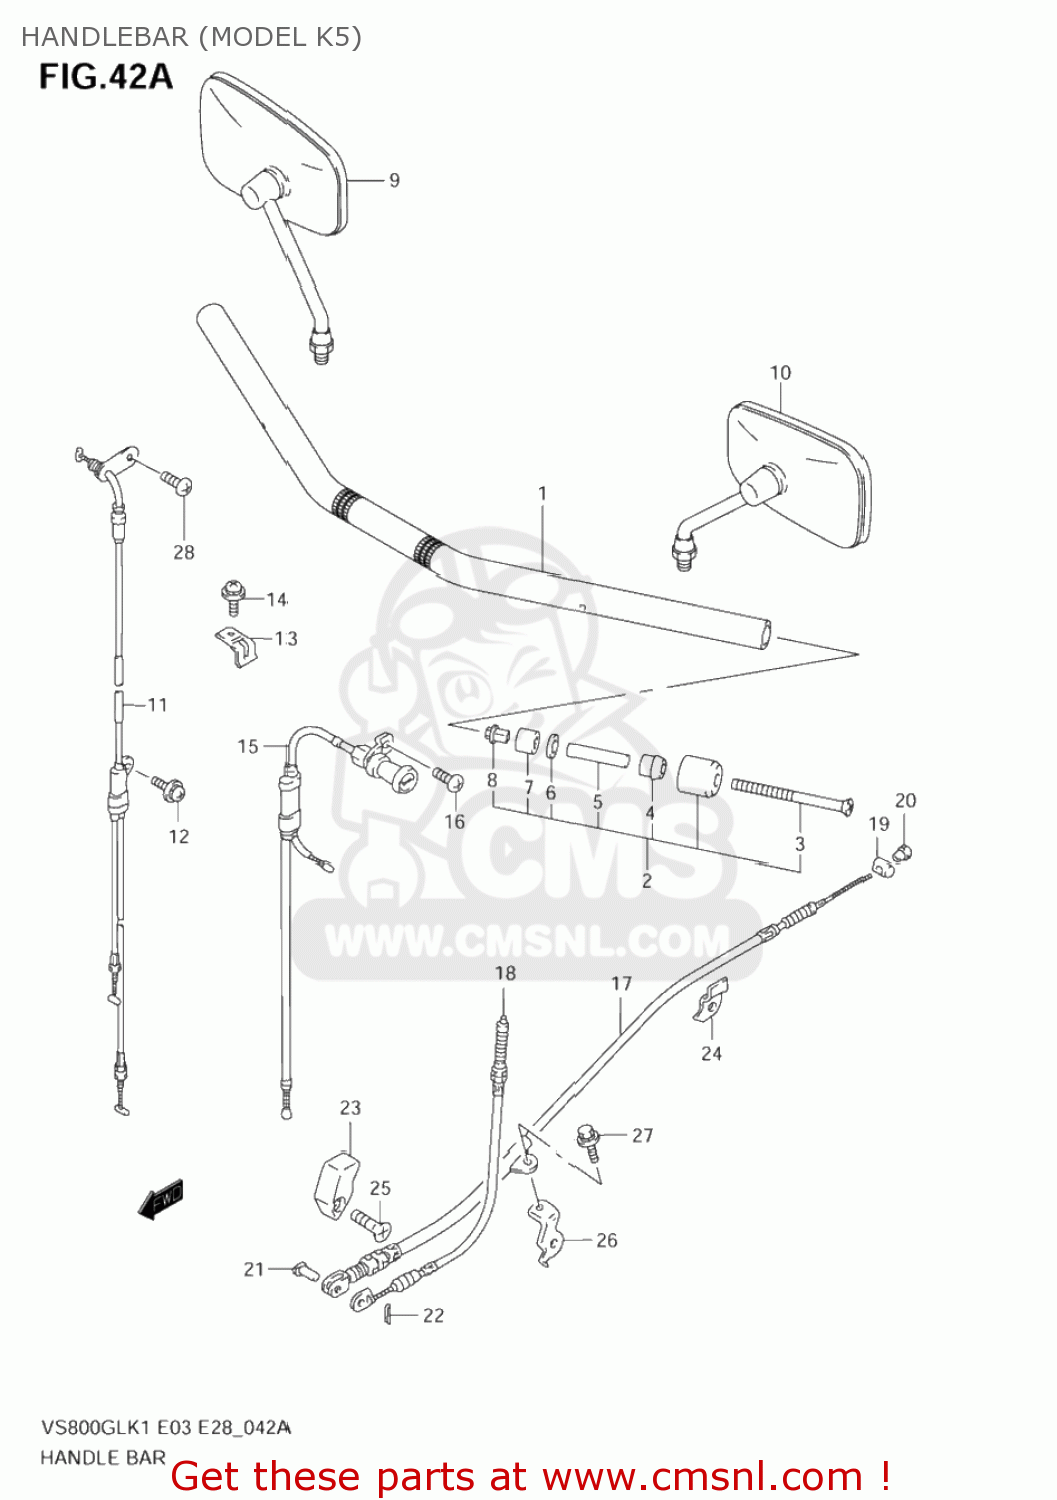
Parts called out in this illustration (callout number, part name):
1	HANDLEBAR
2	BALANCER SET, HANDLEBAR
3	SCREW(6X110)
4	EXPANDER,HANDLE BALANCER NO.2
5	SPACER,EXPANDER
6	WASHER(6.5X16X4)
7	EXPANDER, INNER
8	NUT,HANDLE BAL
9	MIRROR ASSY, REAR VIEW RH
10	MIRROR ASSY,RH
11	CABLE ASSY,THROTTLE
12	SCREW
13	CLAMP,THROTTLE CABLE
14	SCREW
15	CABLE ASSY,STARTER
16	SCREW 6X10
17	CABLE,RR BRAKE
18	CABLE,STOP LAMP SWITCH
19	PIN(13X18)
20	NUT
21	PIN(L:17.5)
22	PIN
23	GUIDE,RR BRAKE CABLE
24	CLAMP,RR BRAKE CABLE
25	SCREW
26	BRACKET,RR BRAKE CABLE
27	BOLT
28	SCREW(5X10)
